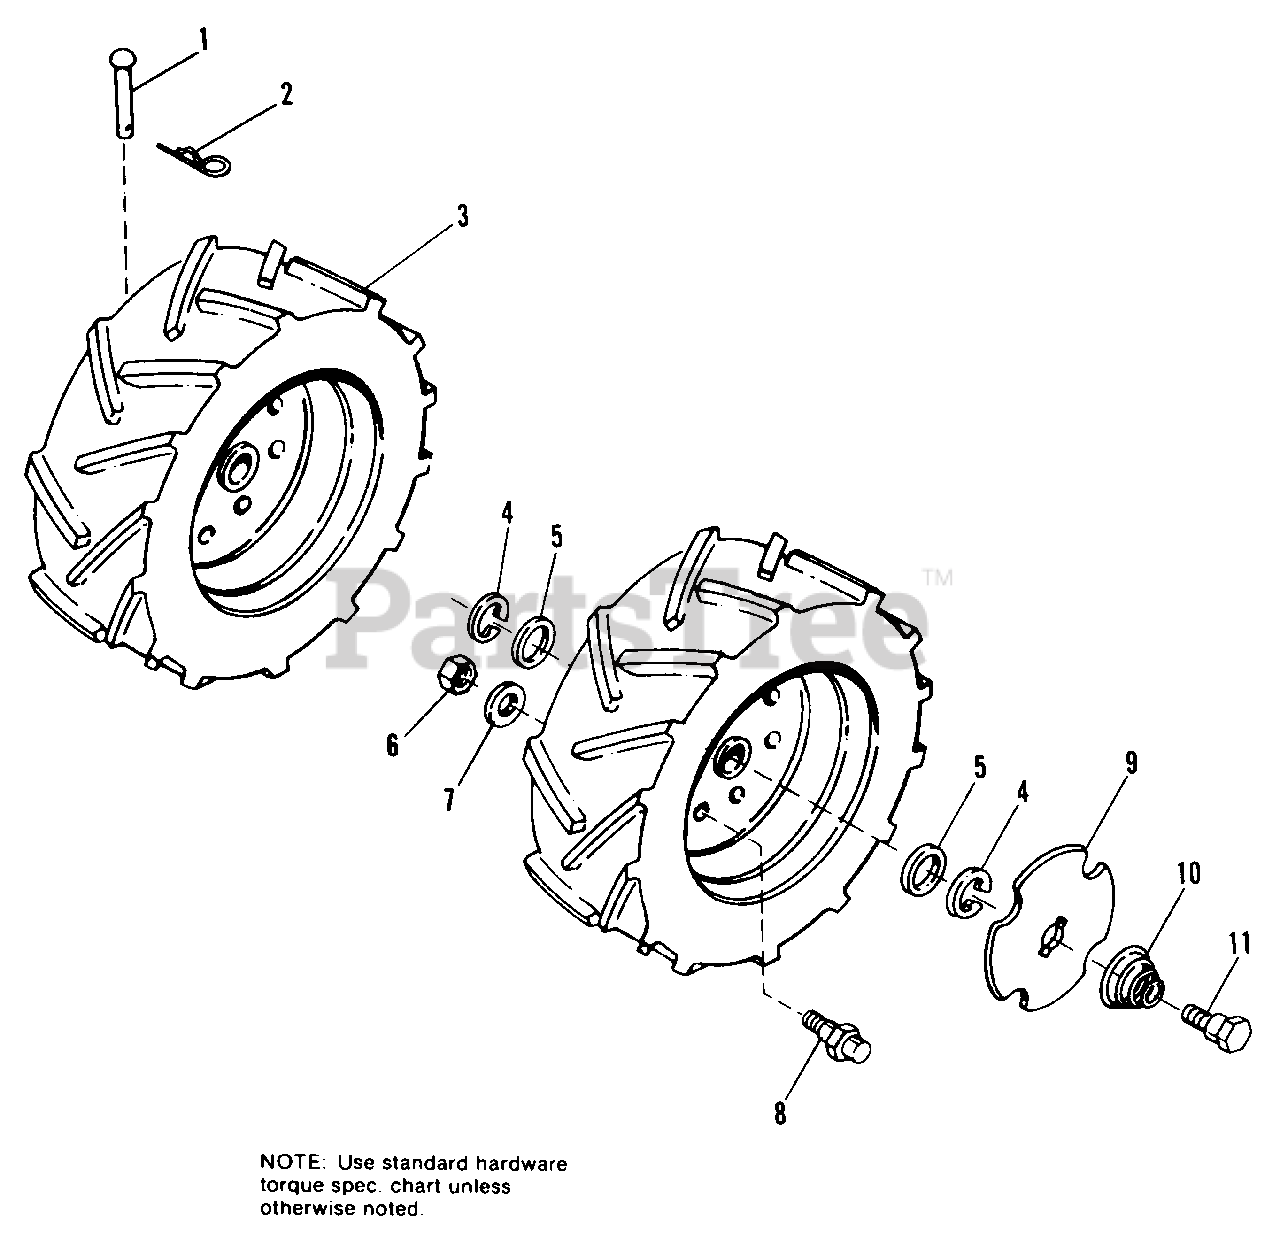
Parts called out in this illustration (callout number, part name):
1	PIN
2	CLIP, Spring
3	WHEEL & TIRE ASSY.
4	RING, Retaining
6	LOCKNUT, Hex, 3/8-16
7	WASHER, Plain, 5/16
11	BOLT, Shoulder
